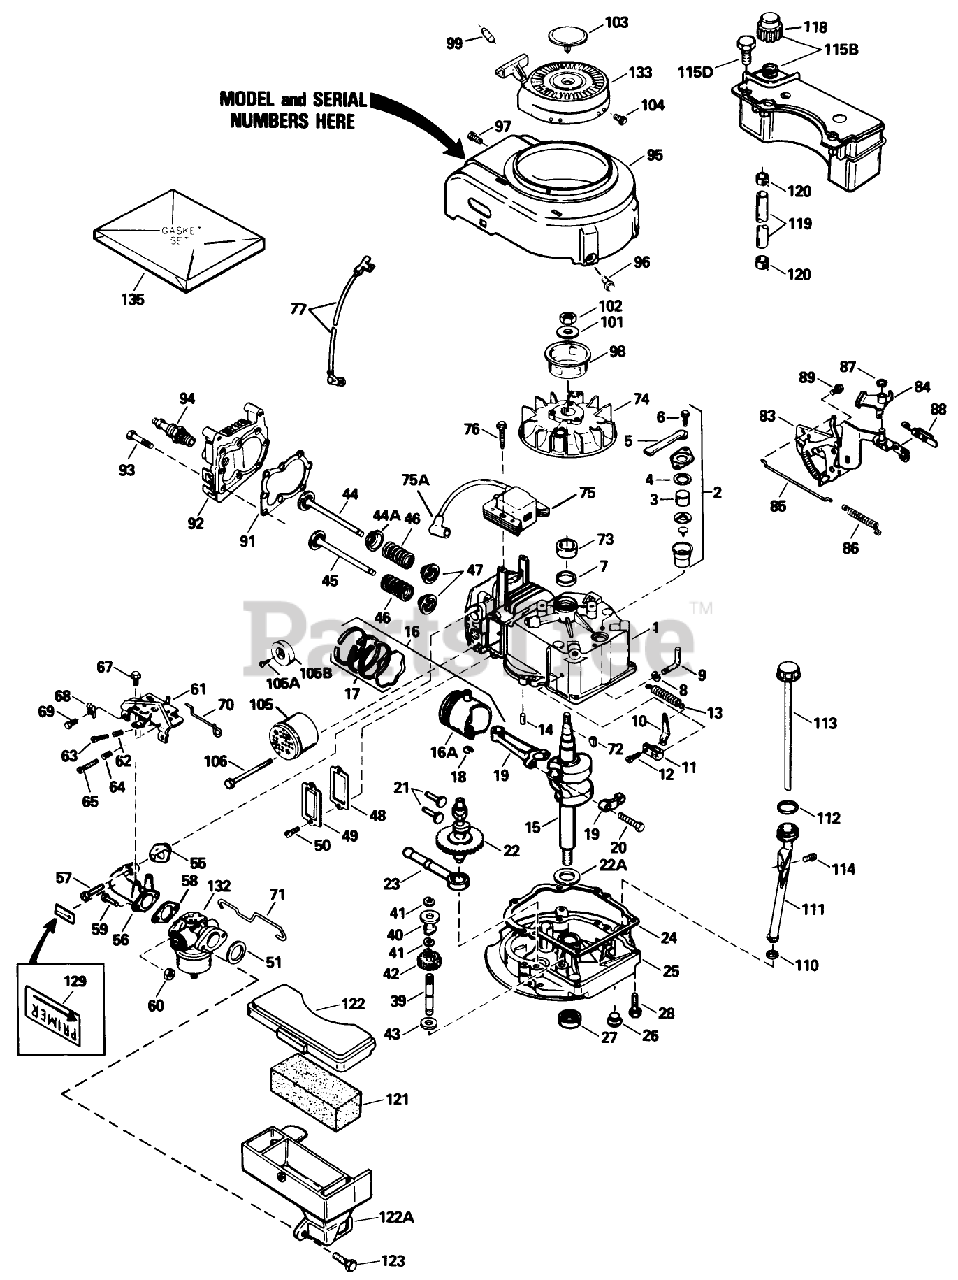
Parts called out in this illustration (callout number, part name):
1	Cylinder Assy. (Incl. #24)
2	Breather Assy. (Incl. Ref. #46 thru 51)
3	Element-Breather
4	Gasket-Breather
5	Tube, Breaker
6	Screw (10-24 x 9/16)
7	Seal-Oil
8	Washer-Flat
9	Rod, Governor (Incl. No. 36)
10	Governor Lever
11	Clamp-Lever, Governor
12	Screw
13	Spring Governor
14	Pin-Dowel
15	Crankshaft
16	Piston-Pin Ring Assy. (Std.)(Incl. Ref. #16A, 17 18)
16	Piston-Pin Ring Assembly (.010 oversize)(Incl. Ref. #16A, 17 18)
16	Piston, Pin Ring Assy. (.020 Oversize)(Incl. Ref. #13A, 14, 15)
16A	Piston Pin Assy. (Std.)(Incl. Ref. #14)
16A	Piston Pin Assembly (.010 oversize)(Incl. Ref. #18)
16A	Piston Pin Assy. (.020 Oversize) (Incl. Ref. #14)
17	Ring Set-Piston (Std.)
17	Ring Set, Piston(.0100versize)
17	Ring Set (.020" OS)
18	Ring-Retaining, Piston Pin
19	Rod Assy., Connecting (Incl. Ref. #17)
20	Bolt-Rod, Connecting
21	Lifter-Valve
22	Camshaft(Mech.Comp. Release)
22A	Washer-Thrust
23	Oil Pump ASM
24	Gasket
25	Flange-Mounting (Incl. Ref. #26, 27 39)
26	Plug Oil Drain
27	Seal-Oil
28	Screw (1/4-20 x 1-1/4)
39	Shaft-Governor
40	Spool-Governor
41	Ring-Retaining
42	Governor Gear ASM
43	Washer
44	Valve, Intake (Std.) (Incl. Ref. #40)
44	Valve, Intake (1/32" oversize)(Incl. No. 40)
44A	Seal Assy., Intake
45	Valve, Exhaust (Std.)(Incl. No. 40)
45	Valve, Intake (1/32" oversize)(Incl. No. 40)
46	Spring-Valve
47	Cap-Valve, Spring
48	Gasket-Cover, Valve
49	Cover-Valve
50	Screw
51	Gasket-Cleaner, Air
55	Gasket-Intake Pipe
56	Pipe-Intake (Incl. Ref. #59)
57	Screw (1/4-20 x 1)
58	Gasket
60	Nut and Lock Washer (1/4-28)
61	Control Assy.-Remote Speed (Incl. Ref. #69 thru 72 76)
62	61709/GIL1515A/95-5
63	Screw
64	Spring-Compression
65	Screw
67	Screw (10-24 x 9/16)
68	Conduit
69	Screw (10-32 x 3/8)
70	2035A67 ADD.ASSEMBL
71	Link-Throttle
72	Key-Flywheel
73	Spacer
74	Flywheel
75	Solid State
75A	Cover-Spark Plug
76	Screw
77	Ground Wire
83	Bracket-S.E. Brake
84	Lever-Brake
85	Link-Control
86	Spring-Extension
87	Ring-Retaining
88	Terminal
89	Screw (1/4-20 x 3/8)
91	Gasket-Cylinder Head
92	Head-Cylinder
93	Screw (5/16-18x1-1/2)
94	Spark Plug-Resistor (R J19 L M)
95	Housing-Blower
96	Screw (1/4-20 x 1/2)
97	Screw (10-24 x 9/16)
98	Hub-Starter
99	Retainer-Starter Rope
101	Washer-Belleville
102	Nut-Flywheel
103	Plug Starter
104	Screw, Hex Hd.
105	Muffler Assembly (Incl. Ref. #106)
105A	Cover-Muffler
105B	Screw (8-32 x 3/8)
106	Screw
110	Gasket
111	Oil Fill Tube
112	O-Ring
113	Dipstick
114	Screw (10-32 x 1/2)
115B	Tank Assembly-Fuel (Incl. Ref. #102)
115D	Screw (10-32 x 35/64)
118	Cap-Fuel
119	Line-Fuel
120	Clamp-Line, Fuel
121	Filter-Air Cleaner
122	Cover-Air Cleaner
122A	Body Air cleaner
123	Screw
129	Decal-Primer
132	Carburetor (Incl. Ref. #83)
133	Starter-Rewind
135	Gasket Set (Incl. Items Marked *)
